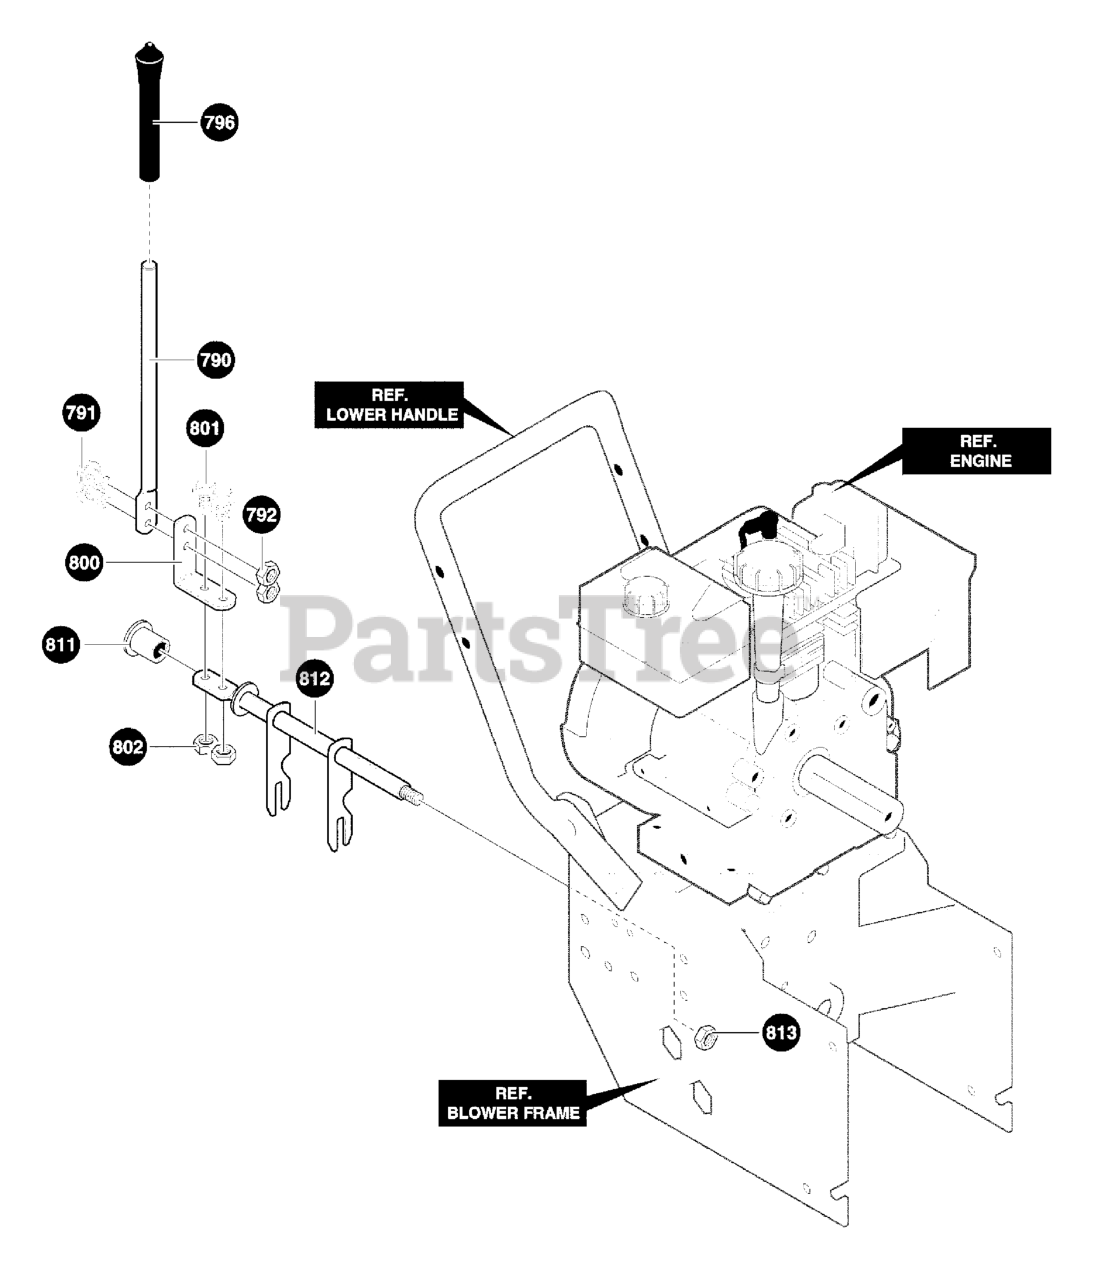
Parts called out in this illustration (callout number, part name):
790	ROD, SHIFT
792	NUT
796	KNOB, SLIP
800	LEVER, SPRING
802	NUT
811	BEARING, FLANGE
812	ROD, ASSY YOKE
813	NUT, HEX
